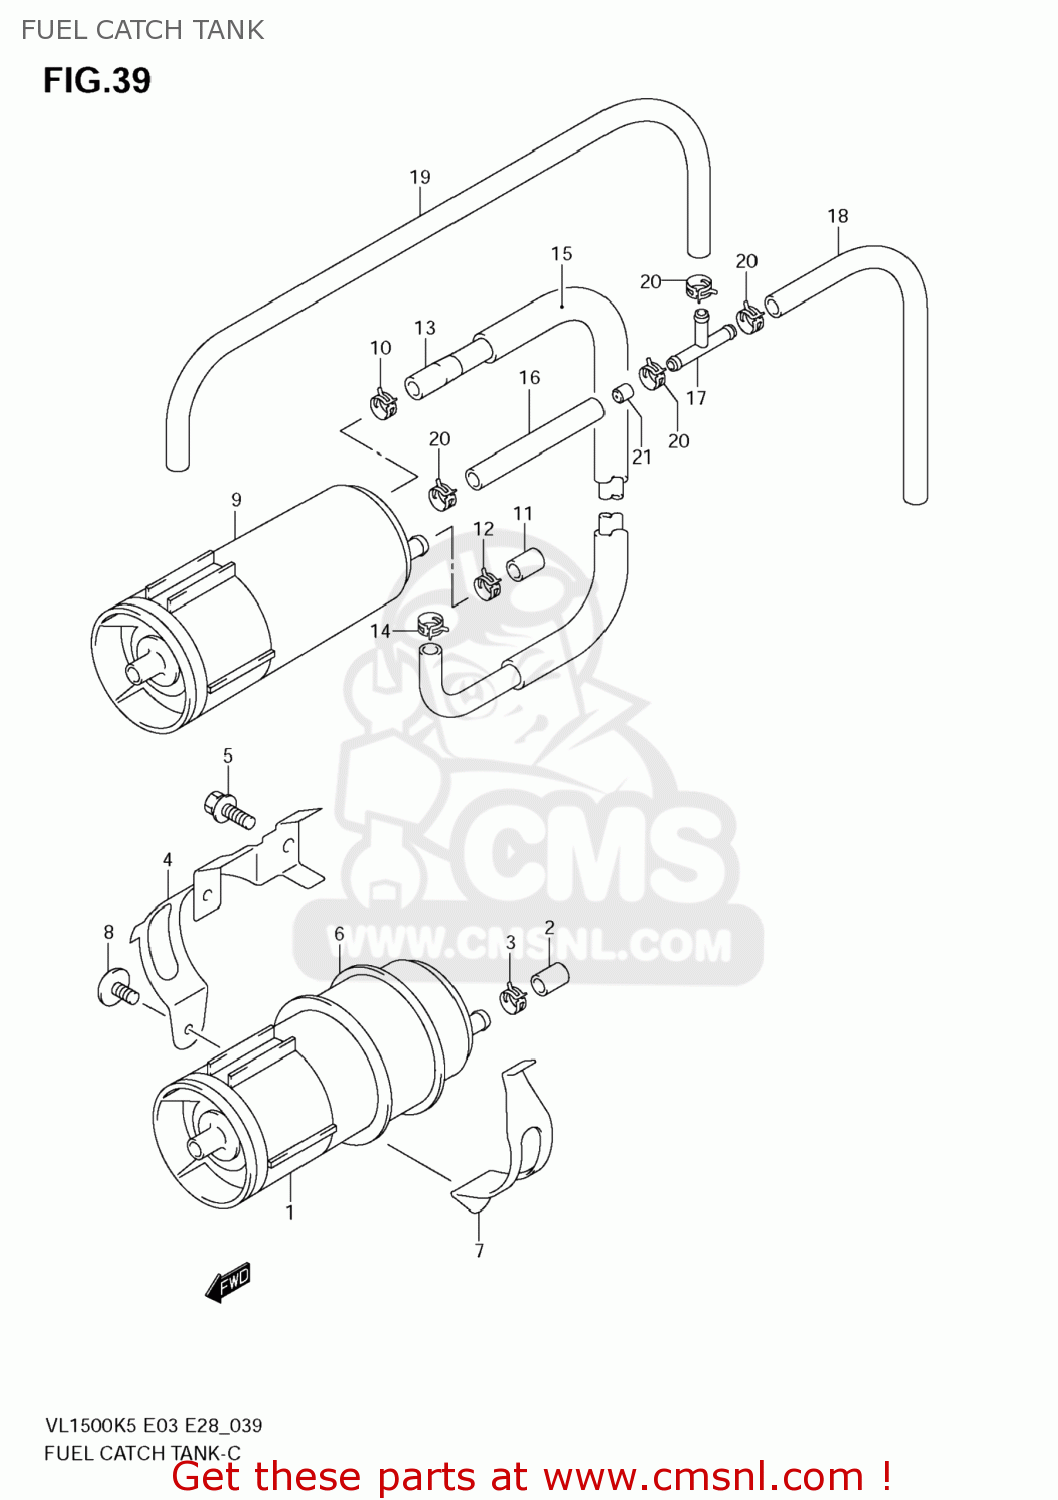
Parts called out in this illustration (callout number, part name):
1	TANK,FUEL CATCH
2	CAP,OD:11.5
3	CLIP
4	BRACKET,CATCH TANK
5	BOLT(6X16)
6	CUSHION,CANISTER
7	HOLDER,CATCH TANK
8	SCREW
9	CANISTER ASSY,CHARCOAL
10	CLIP
11	CAP,OD:11.5
12	CLIP
13	HOSE,CANISTER PURGE
14	CLIP
15	PROTECTOR(14.5X15.5X600)
16	HOSE(5.4X11.4X600)
17	JOINT
18	HOSE(5.4X11.4X600)
19	HOSE(5.4X11.4X600)
20	CLIP
21	PIPE
